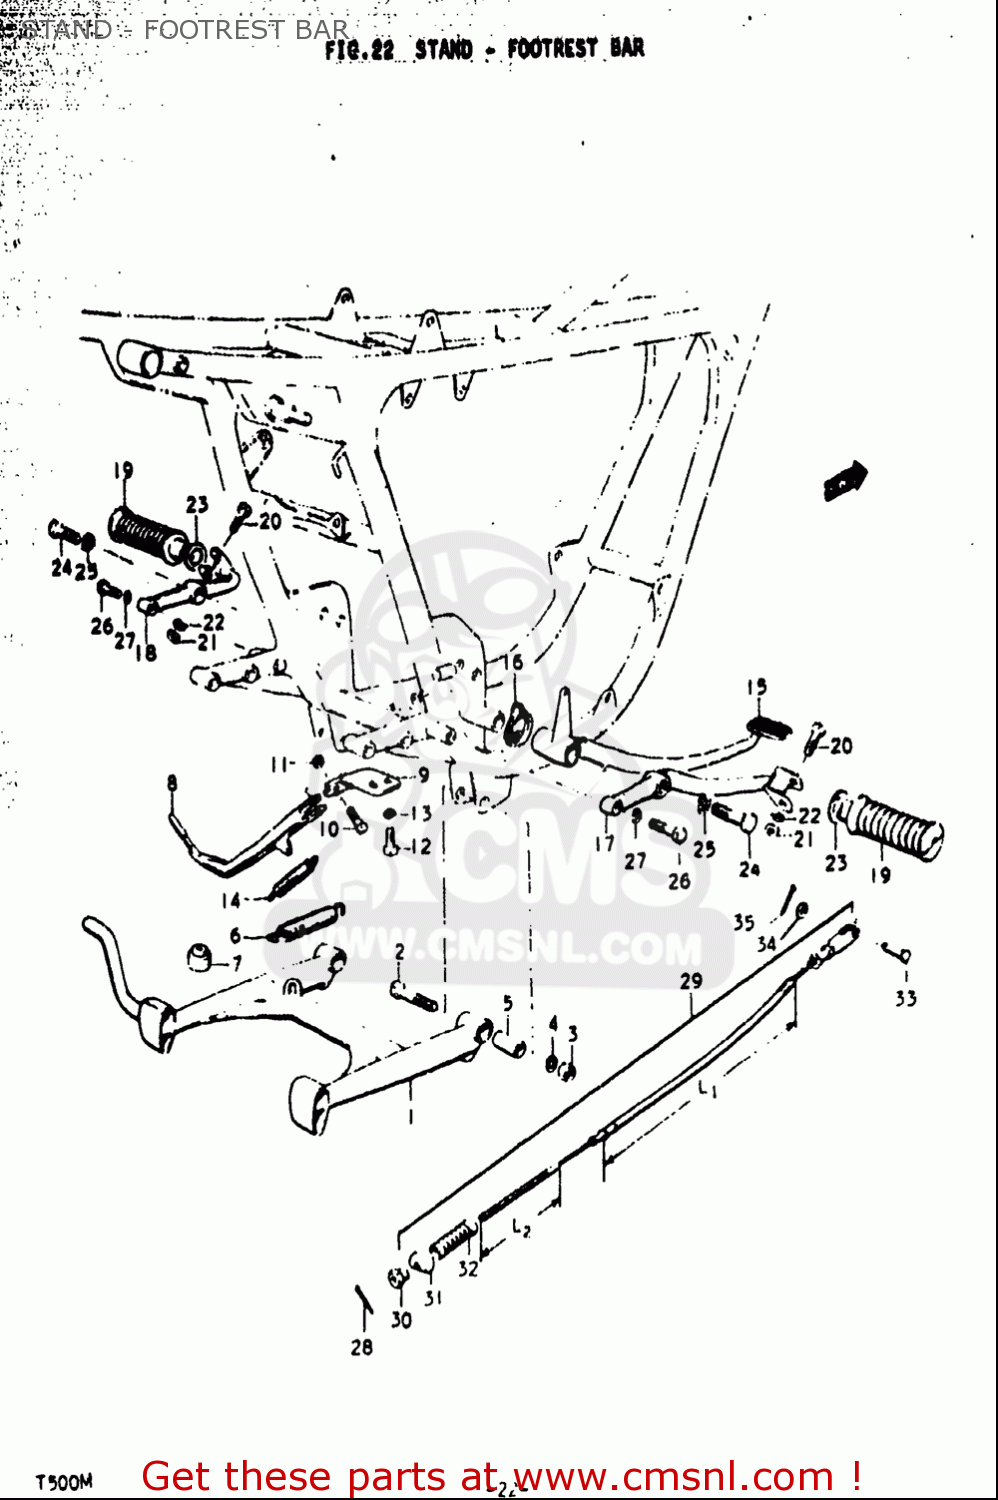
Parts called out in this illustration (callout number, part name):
2	BOLT(10X48)
3	NUT
4	WASHER,LOCK
5	SPACER(10.5X16X30)
6	SPRING
7	CUSHION
10	BOLT(10X27)
11	NUT
12	BOLT
13	WASHER,LOCK
14	SPRING
16	SPRING
21	NUT
22	WASHER
23	WASHER(22.5X38X1)
24	PIN
25	WASHER,LOCK
26	BOLT
27	WASHER,LOCK
28	BOLT(12X45)
30	NUT
31	PIN(13X18)
32	SEAL,DUST
33	PIN(L:17.5)
34	WASHER
35	PIN
